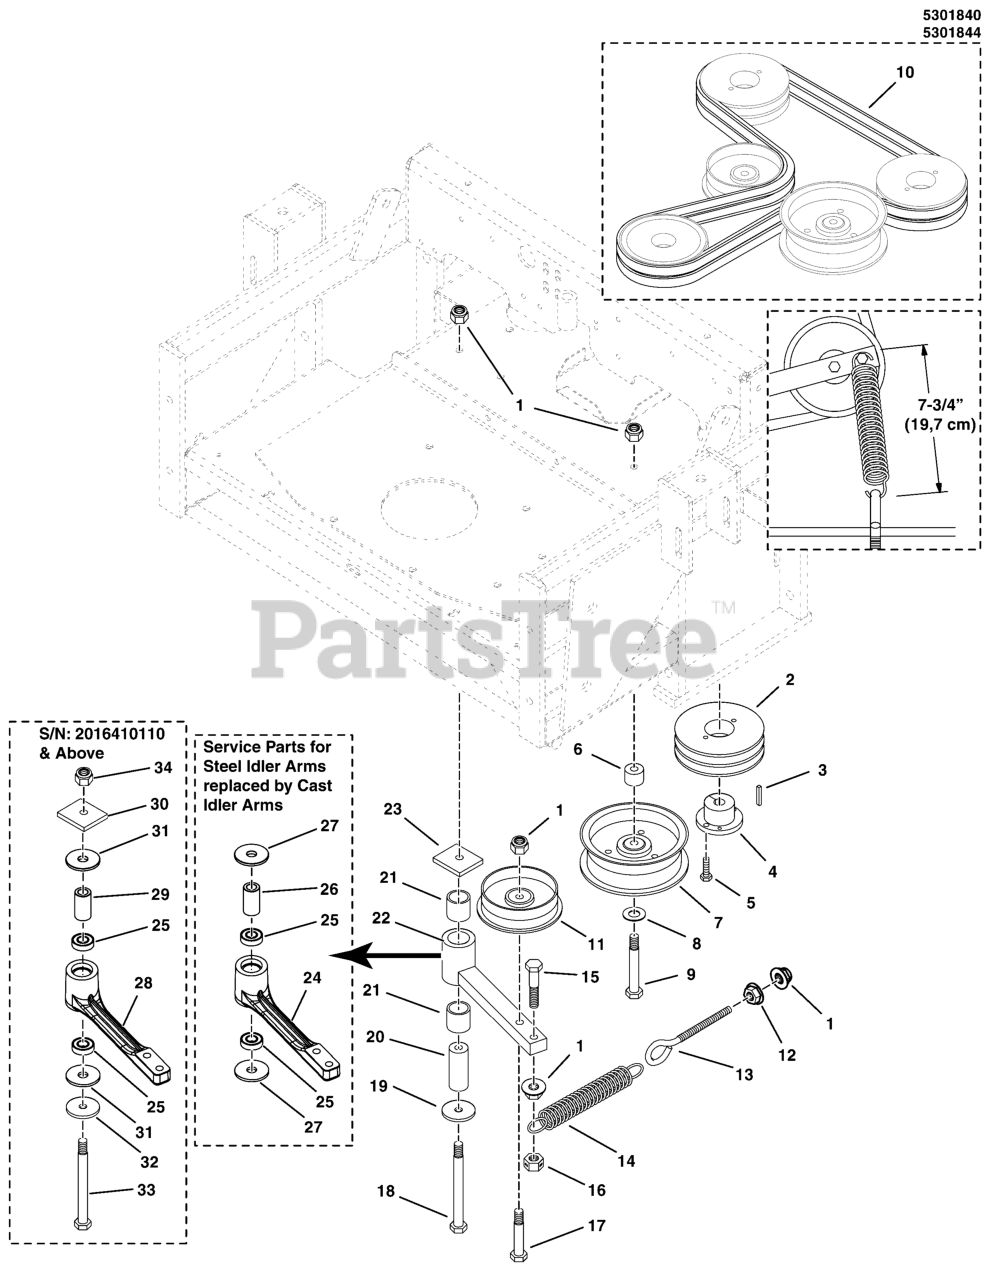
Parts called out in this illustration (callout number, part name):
1	NUT, 3/8 - 16 HEX NYLOCK FLANGE
2	PULLEY, 5.45 OD, DOUBLE GROOVE
3	KEY, 5 MM SQ W/ RADIUS
4	BUSHING, 17MM, HQ
5	BOLT, 1/4-20 X 1" GD5 CZ
6	SPACER, .39 X 1.00 X .80
7	PULLEY, IDLER 5"
8	WASHER, 3/8 SAE
9	BOLT, 3/8-16 X 2-1/4" GD5 CZ
9	BOLT, 3/8-16 X 2-1/2" GD5 CZ
10	BELT, A-SEC, 69.5EL, POLYESTER, RAW EDGE
11	PULLEY, IDLER, SINGLE FLANGE
12	NUT, 3/8-16 HEX SERRATED FLANGE
13	EYE BOLT, 3/8-16 X 6.88, 3THRD, 1EYE
14	SPRING, EXTENSION, SWIVEL END
15	BOLT, 3/8-16 X 1-3/4" GD5 CZ
16	NUT, 3/8-16 HEX SIDE LOCK
17	BOLT, 3/8-16 X 2-1/4" GD5 CZ
18	BOLT, 3/8-16 X 4" GD5 CZ
19	WASHER, .41 X 1.75 X .14
20	SPACER, .39 X 1.00 X 2.55, SS
21	BUSHING, BRASS, 1.25X1.0X1.25
23	SPACER, IDLER PIVOT
24	ASSM, IDLER ARM, PUMP DRIVE, 3/8ID, CAST
25	BEARING, BALL AXLE
26	SPACER, .39 X .88 X 1.53, CZ
27	SPACER, IDLER ARM, T-STYLE, CZ
28	ASSM, IDLER ARM, PUMP DRIVE, 1/2ID, CAST
29	SPACER, .52 X .84 X 1.53, PM
30	SPACER, .52ID X 2X1.75RCT X .25, CZ
31	SPACER, IDLER ARM, 1/2 PM
32	WASHER, .52 X 1.75 X .14, CZ
33	BOLT, 1/2-13 X 4" GD5 CZ
34	NUT, Hex Flange, Nylock, 1/2-13
